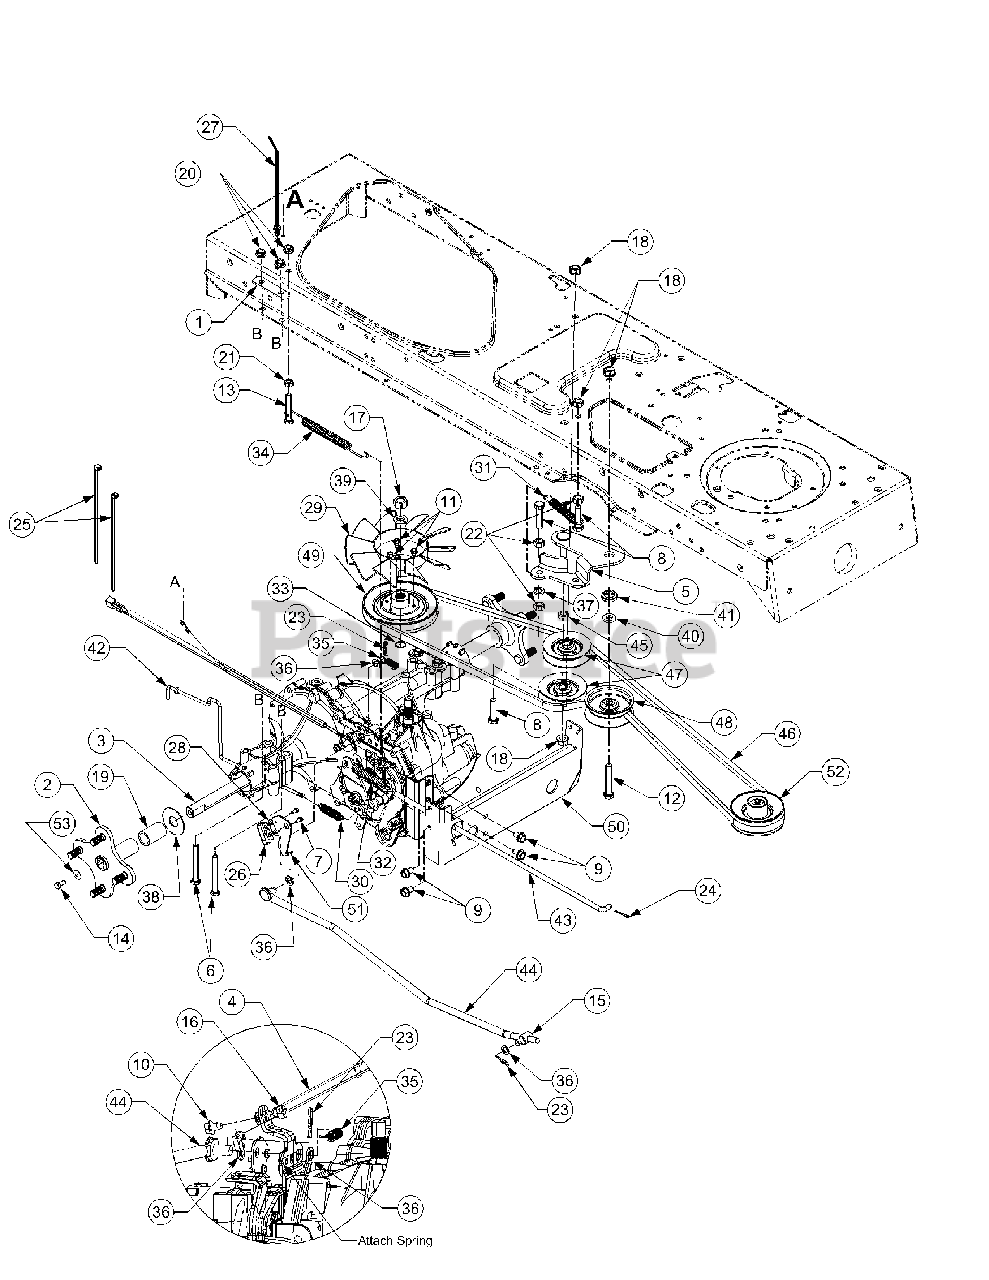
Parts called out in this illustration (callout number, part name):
2	Hub Assembly, Wheel (Double "D")
3	Transmission, Hydrostatic (Uses Double "D" axle)
4	Harness Assembly, Ground & Reverse
6	Hex Cap Screw, 5/16-18,3.5, Gr5
7	Screw, #8-18, 0.500
8	Hex Cap Screw, 3/8-16, 1.50, Gr5
9	Screw, 5/16-12, 0.75
10	Screw, 1/4-20, 0.5
11	Screw, #12-24, 0.375
12	Hex Cap Screw, 3/8-16, 2.25, Gr5
13	Hex Cap Screw, 5/16-18, 2.00, Gr5
14	Hex Cap Screw, 5/16-24 x .750 (Use with Double "D" hub
15	Ferrule, 3/8-24 x .375 Dia
16	Nut, Hex Lock, 1/4-20
17	Nut, Hex, 1/2-20, Gr2
18	Nut, Nylon Lock, 3/8-16
19	Sleeve, 1.5"
20	Nut, Nylon Lock, 5/16-18, Gr5
21	Nut, Hex, 5/16-18, Gr5
22	Nut, Hex, 3/8-16, Gr8
23	Pin, Cotter, .072 Dia. x 1.13 Lg
24	Pin, Cotter, 3/32, 1.0
25	Cable, Tie, 3/16 x .05 x 7.4
26	Switch, Spring, Short
27	Tie, Cable, Push Mount 7.5 Lg
28	Plate, Insulator Nut
29	Fan, Blade, 10"
30	Spring, .48 OD x 2.03 Extension
31	Spring, Extension, .50 Dia x 3.97 Lg
32	Spring, Extension, .59 OD x 4.00 Lg
33	Ring, Wire
34	Spring, Extension, .500 Dia x 7.0 Lg
35	Spring, Extension, 3/8 OD x 1.44 Lg
36	Washer, Flat, .385 x .62 x .063
37	Washer, Lock, 3/8, Regular Duty
38	Washer, Flat, .755 x 1.92 x .060
39	Washer, Lock, 1/2, Regular Duty
40	Washer, Flat, .407 x .812 x .135 Hdn
41	Spacer, Shoulder, 1.00 x .38 x .38
42	Rod, Hydro Bypass
43	Rod, Brake, Hydro
44	Rod, Control, Hydro
45	Spacer, .376 ID x .625 OD x .22
46	Belt, V Type, Poly Ax 79.2 Lg
47	Pulley, Idler, V Type x 3.06 Dia
48	Pulley, Idler, Flat 2.75 OD
49	Pulley, Input, 5.0 Dia S/N 1A174H20368 & before
52	Pulley, Engine, 3.56 Dia.
53	Belle Washer
